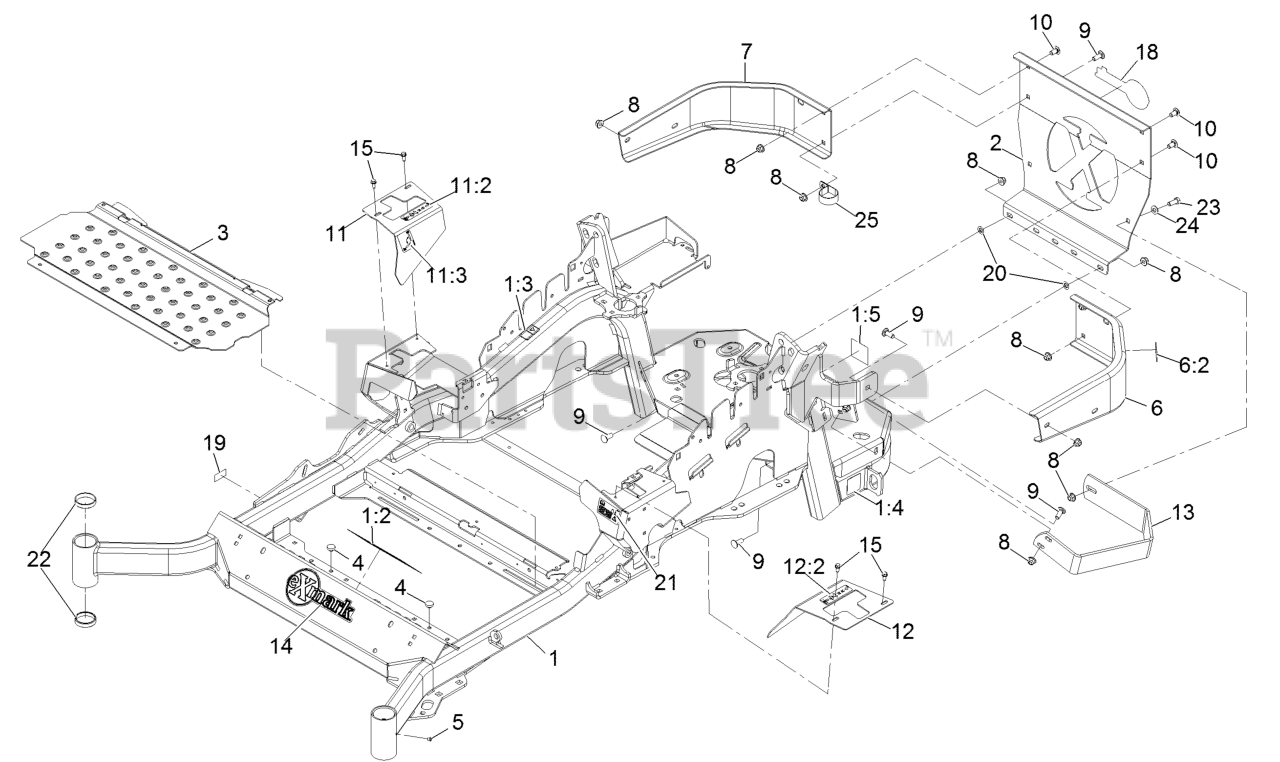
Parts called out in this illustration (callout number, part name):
1:2	DECAL-DANGER
1:3	DECAL-WARNING
1:4	DECAL-HAZARD, PINCHED FINGER
1:5	DECAL-SPARK ARRESTER
2	PLATE,REAR GUARD
6	LH BUMPER ASM
6:2	DECAL-WARNING
7	BUMPER-RH
8	NUT-HF, NI
9	SCREW-CARR
10	SCREW-CARR
11	RH MOTION CONTROL COVER ASM
11:2	DECAL-CONTROL, MOTION
11:3	DECAL-PARK BRAKE, CE
12	LH MOTION CONTROL COVER ASM
12:2	DECAL-CONTROL, MOTION
13	GUARD-MUFFLER
14	DECAL-EXMARK LOGO
15	SCREW-HWH
18	DECAL-EXMARK LOGO
19	Decal-Patent Ttco.Com
20	NUT-PUSH
21	DECAL-FUEL FILL, CE
22	CUP-BEARING
23	SCREW-HH
24	WASHER-FLAT
25	CLAMP-R
